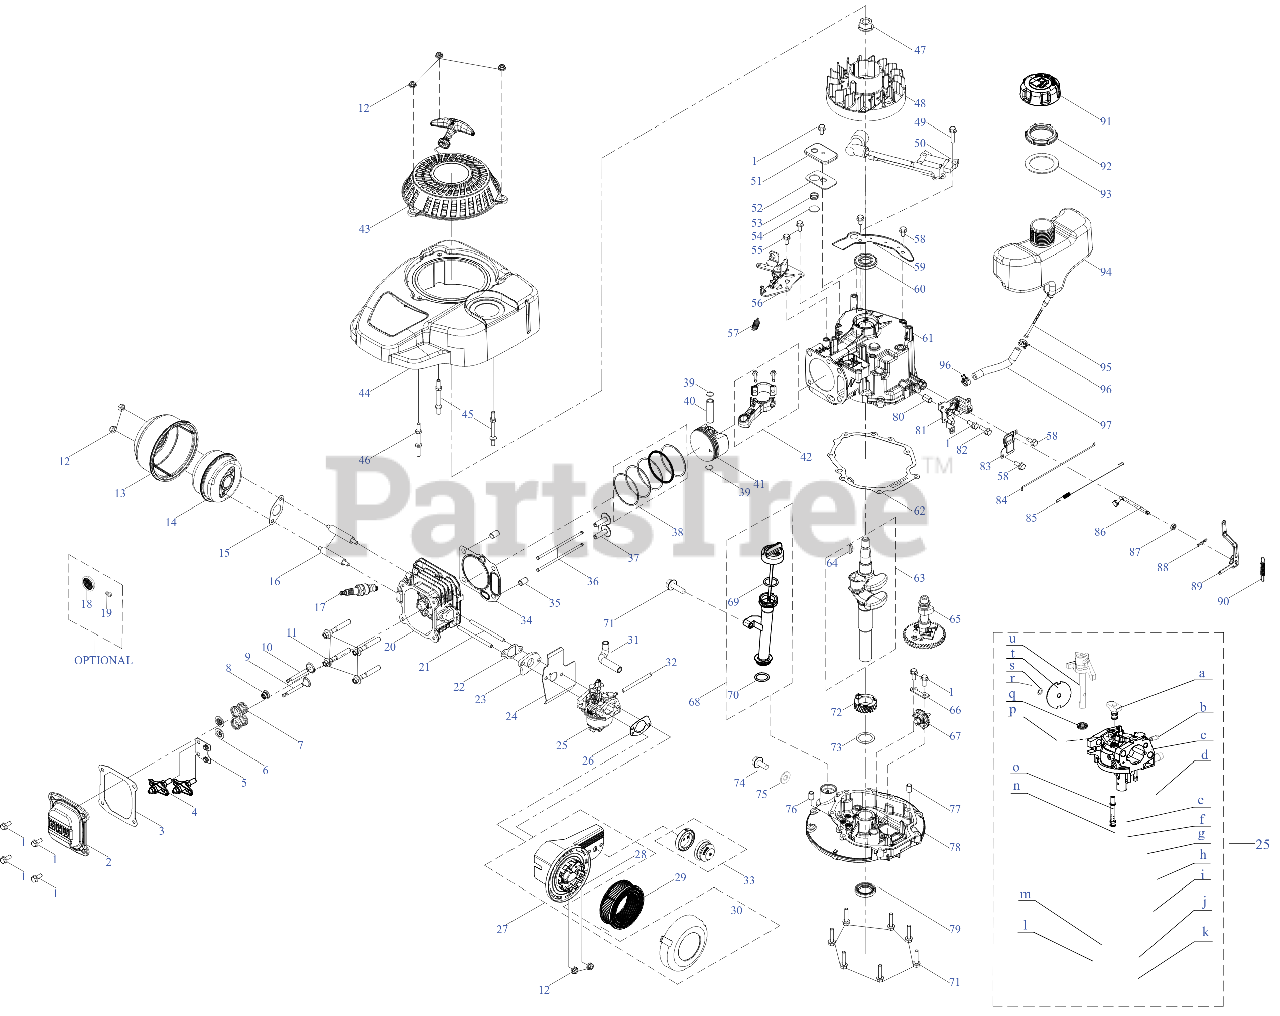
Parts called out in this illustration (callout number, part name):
1	BOLT M6-1 x 14 GR8.8
2	VALVE COVER
3	VALVE COVER GASKET
4	ROCKER ARM ASSEMBLY
5	PUSH ROD GUIDE
6	VALVE SPRING RETAINER
7	VALVE SPRING
8	INTAKE VALVE SEAL
9	EXHAUST VALVE
10	INTAKE VALVE
11	SCREW M8 x 54 GR10
13	MUFFLER SHIELD
14	MUFFLER ASSEMBLY
15	MUFFLER GASKET
16	STUD M6-1 x 76
17	SPARK PLUG
18	SPARK ARRESTOR
19	SCREW M3.5 x 9.5
20	CYLINDER HEAD
21	STUD M6 x 98
22	CARBURETOR INSULATOR GASKET
23	CARBURETOR INSULATOR
24	CARBURETOR GASKET
25	CARBURETOR
26	AIR FILTER BASE GASKET
27	AIR FILTER ASSEMBLY
28	AIR FILTER BASE
29	PAPER AIR FILTER
30	AIR FILTER COVER
31	BREATHER HOSE
32	PRIMER HOSE
33	VENTED PRIMER ASSEMBLY
34	CYLINDER HEAD GASKET
36	PUSH ROD
37	TAPPET (LIFTER)
38	PISTON RING SET
39	SNAP RING-PISTON PIN
40	PISTON PIN
41	PISTON
42	CONNECTING ROD ASSEMBLY
43	STARTER RECOIL ASSEMBLY
44	ENGINE SHROUD ASSEMBLY
45	STUD M6 x 75
46	STUD M6 x 73
47	FLYWHEEL NUT
48	FLYWHEEL
49	BOLT M6-1 x 25 GR8.8
50	IGNITION COIL ASSEMBLY
51	BREATHER COVER PLATE
52	BREATHER COVER GASKET
53	BREATHER VALVE SPRING
54	BREATHER VALVE
55	BOLT M6-1 x 12 GR8.8
56	ENGINE BRAKE ASSEMBLY
57	BRAKE SPRING
58	BOLT M6-1 x 10 GR8.8
59	SHROUD COVER PLATE
60	UPPER CRANKSHAFT SEAL
61	CRANKCASE
62	CRANKCASE COVER GASKET
63	CRANKSHAFT
64	FLYWHEEL KEY
65	CAMSHAFT ASSEMBLY
66	GOVERNOR GEAR MOUNTING PLATE
67	GOVERNOR GEAR/SHAFT ASSEMBLY
69	O-RING
71	BOLT-M6-1 x 28 GR8.8
72	CRANKSHAFT TIMING GEAR
73	THRUST WASHER
74	OIL DRAIN PLUG
75	WASHER
76	DOWEL PIN
77	DOWEL PIN
78	CRANKCASE COVER
79	LOWER CRANKSHAFT SEAL
80	Control Bracket Spacer
81	VARIABLE SPEED CONTROL ASSEMBLY
82	BOLT M6-1 x 35 GR8.8
83	VARIABLE SPEED CONTROL COVER
84	THROTTLE LINKAGE
85	THROTTLE LINKAGE SPRING
86	GOVERNOR ARM SHAFT
87	GOVERNOR SEAL
88	COTTER PIN
89	GOVERNOR ARM ASSEMBLY
90	GOVERNOR SPRING
91	FUEL CAP ASSEMBLY
92	FUEL TANK NUT
93	FUEL TANK UPPER GROMMET
95	FUEL FILTER
96	HOSE CLAMP
97	FUEL HOSE
752Z1T65PT	COMPLETE ENGINE
